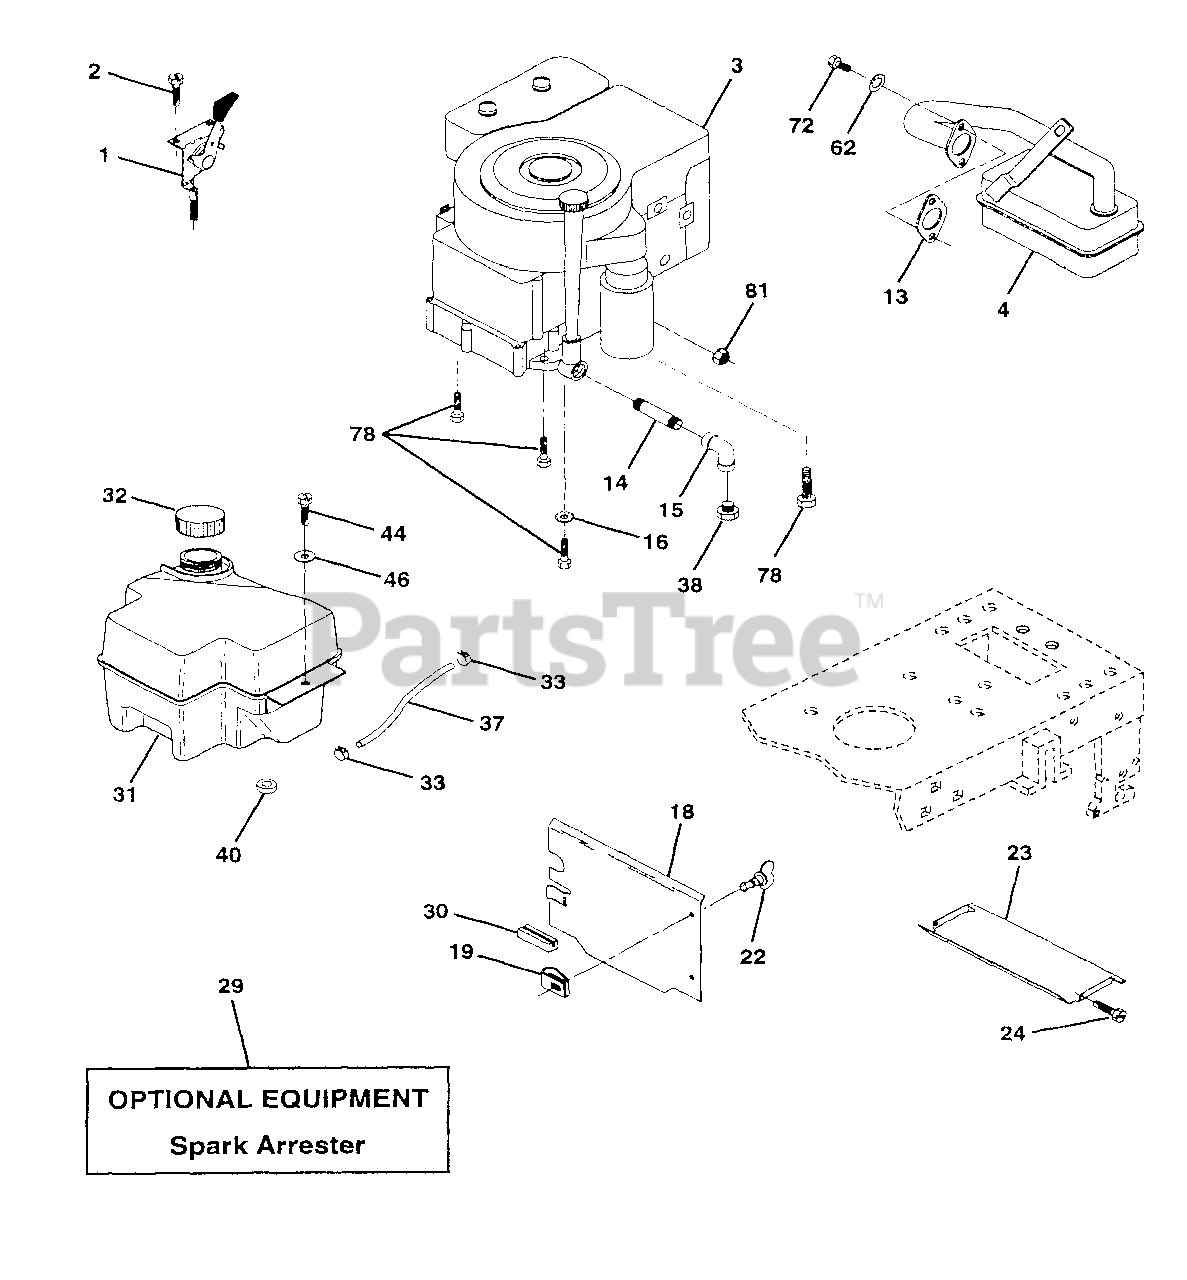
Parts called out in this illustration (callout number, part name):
1	Control Th/ch 23 LH Flag
2	Screw Hex Thd Cut 1/4-20x5/8 T
4	Muffler LT B&S 14 HP IC OHV
13	Gasket Eng 1.313 ID Tin Plated
14	Nipple Pipe 3/8 Npt X 3-1/2
15	Elbow Std 90 Degree 3/8-18 Npt
16	Washer Lock Ext Tooth 318
18	Shield Heat LT
19	Receptacle 1/4 Turn Dacrotized
20	Retainer 1/4 Turn .3650D x .2221 D
21	Washer 9/32 x 5/8 x 16 Ga.
22	Stud 1/4 Turn
23	Shield Heat Browning LT/YT
24	Screw Tap Hex #10-24unc X 1/2
29	Kit Spark Arrestor (Flat Scm)
30	Pinchwelt Black
31	Tank Fuel Front 2 00
32	Cap Asm Fuel w/sym Vented
33	Clamp Hose Black
37	Line Fuel 20"
38	Plug Oil Drain
40	Bushing Snap Ny I Blk Fuel Line
44	Screw Hexwsh Thdrol 1/4-20x3/4
46	Washer 9/32 X 7/8 X 16 Ga
62	Washer Lock Hvy Hlcl Spr 5/16
72	Screw Hex Hd Cap 5/16-18 x 3/4
78	Screw Thdrol. 3/8-16 x 1-1/4 Tytt
81	Nut Flange 1/4-20 Starter Nut
